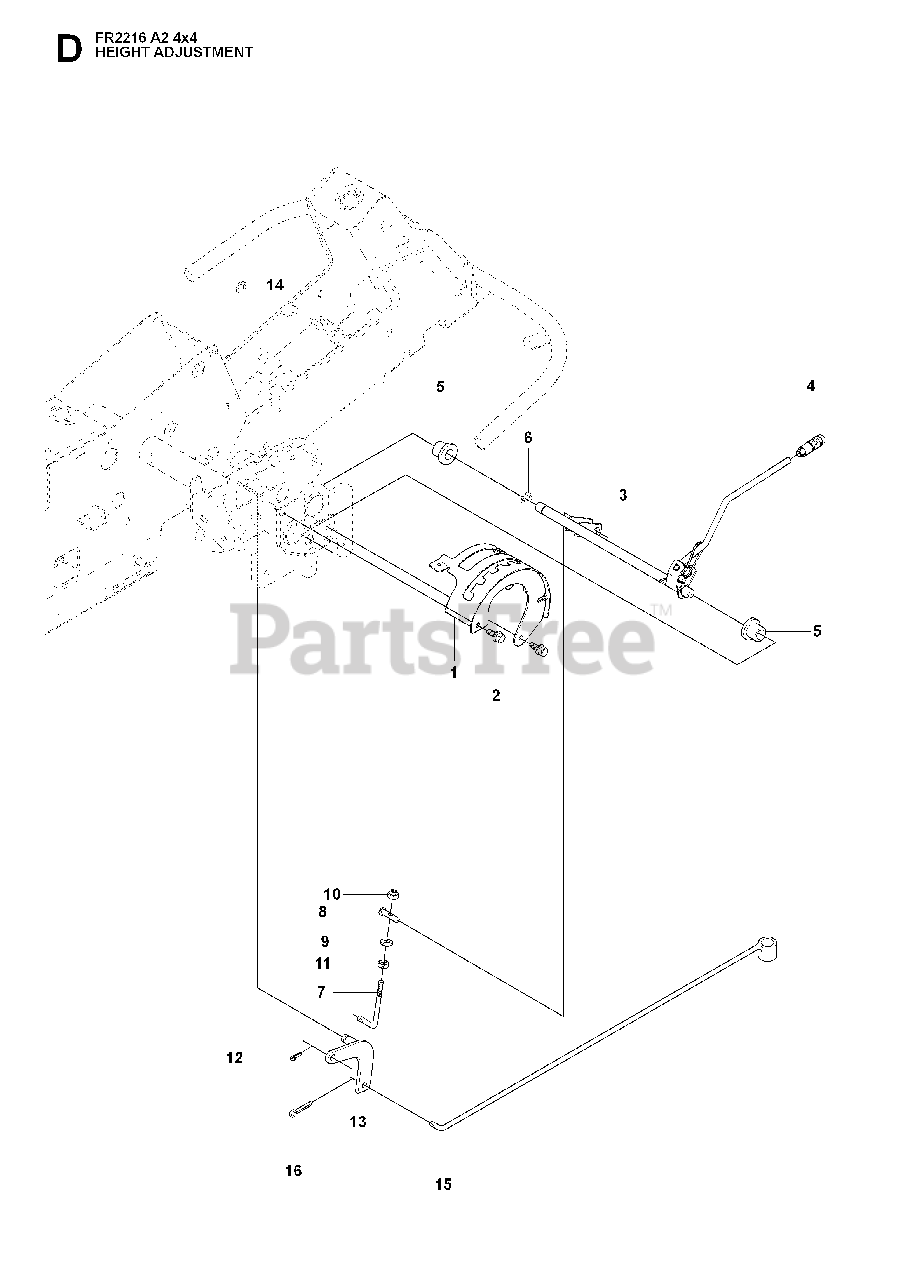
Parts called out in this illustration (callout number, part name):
4	GEAR STICK KNOB
5	BUSHING
9	WASHER
10	LOCKNUT M8
11	NUT
12	SPLIT PIN
14	RETAINING RING
15	CLUTCH ROD
16	SPLIT PIN
